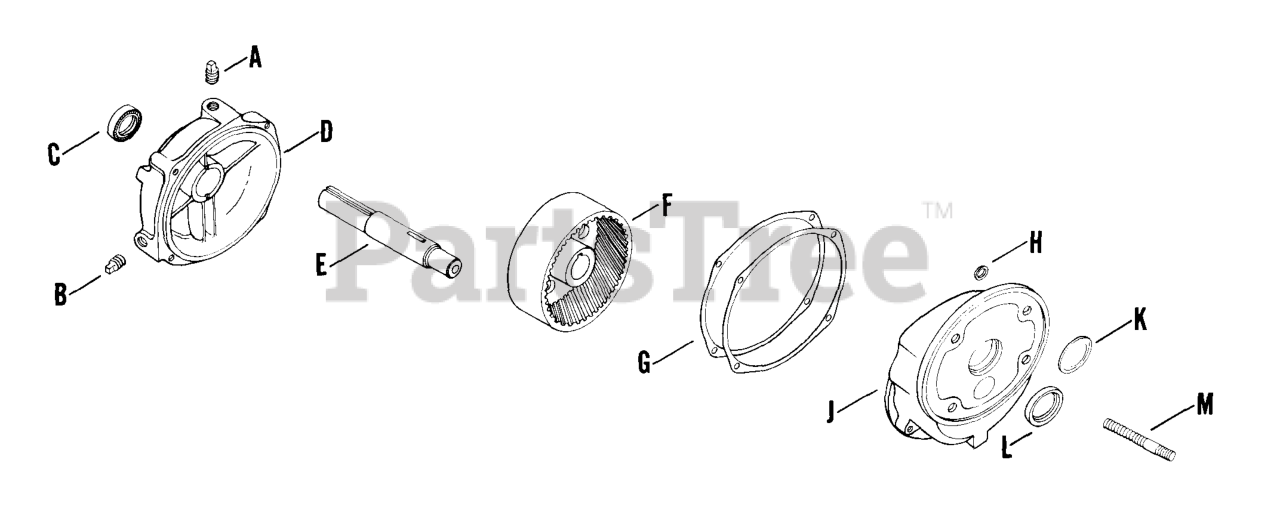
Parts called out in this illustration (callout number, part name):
A	PLUG - USE 41 139 01
B	PLUG,PIPE 1/4 NPTF SQUARE HD USE 25 139 53-S
C	SEAL - DISCONTINUED
D	COVER - DISCONTINUED
E	SHAFT - DISCONTINUED
F	GEAR - DISCONTINUED
G	GASKET - DISCONTINUED
J	HOUSING - USE A-221243
K	PLUG, WELCH EXPANSION
